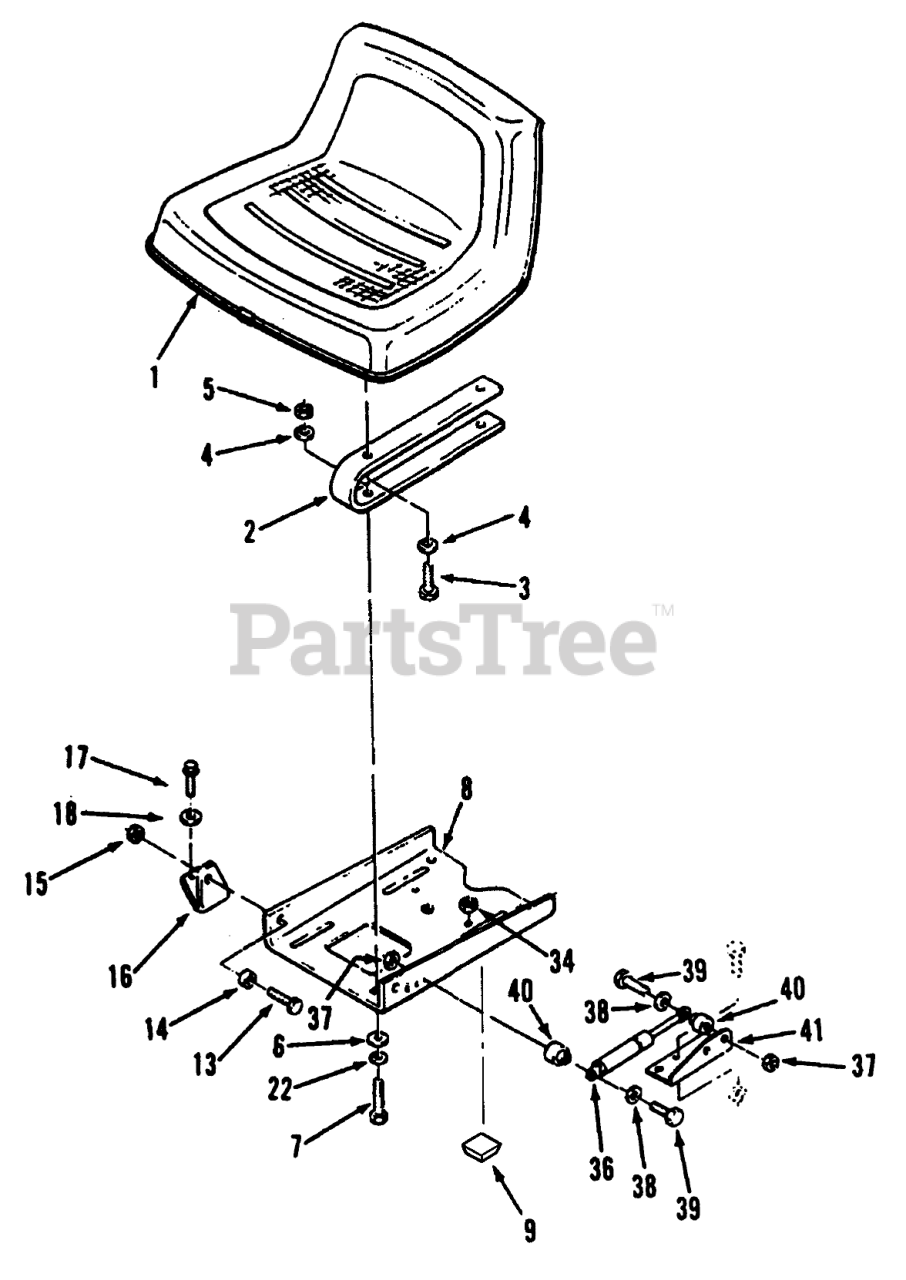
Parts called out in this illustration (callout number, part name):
1	SEAT V-510
2	Seat Spring
3	SCREW-HH
4	WASHER-LOCK
5	NUT-LOCK, NI
6	WASHER-PLAIN
7	SCREW-HH
8	Plate-SeatPivot
9	BUMPER SJ5514 BLACK
13	SCREW-HH
14	BUSHING
15	NUT-LOCK, NI
16	Bracket-Pivot RH
17	Bolt
18	WASHER-PLAIN
22	WASHER-LOCK
34	NUT-LOCK, NI
36	GAS SPRING
37	NUT-LOCK, NI
38	WASHER-FLAT
39	SCREW-HH
40	SPACER
41	BRACKET-CYLINDER R
